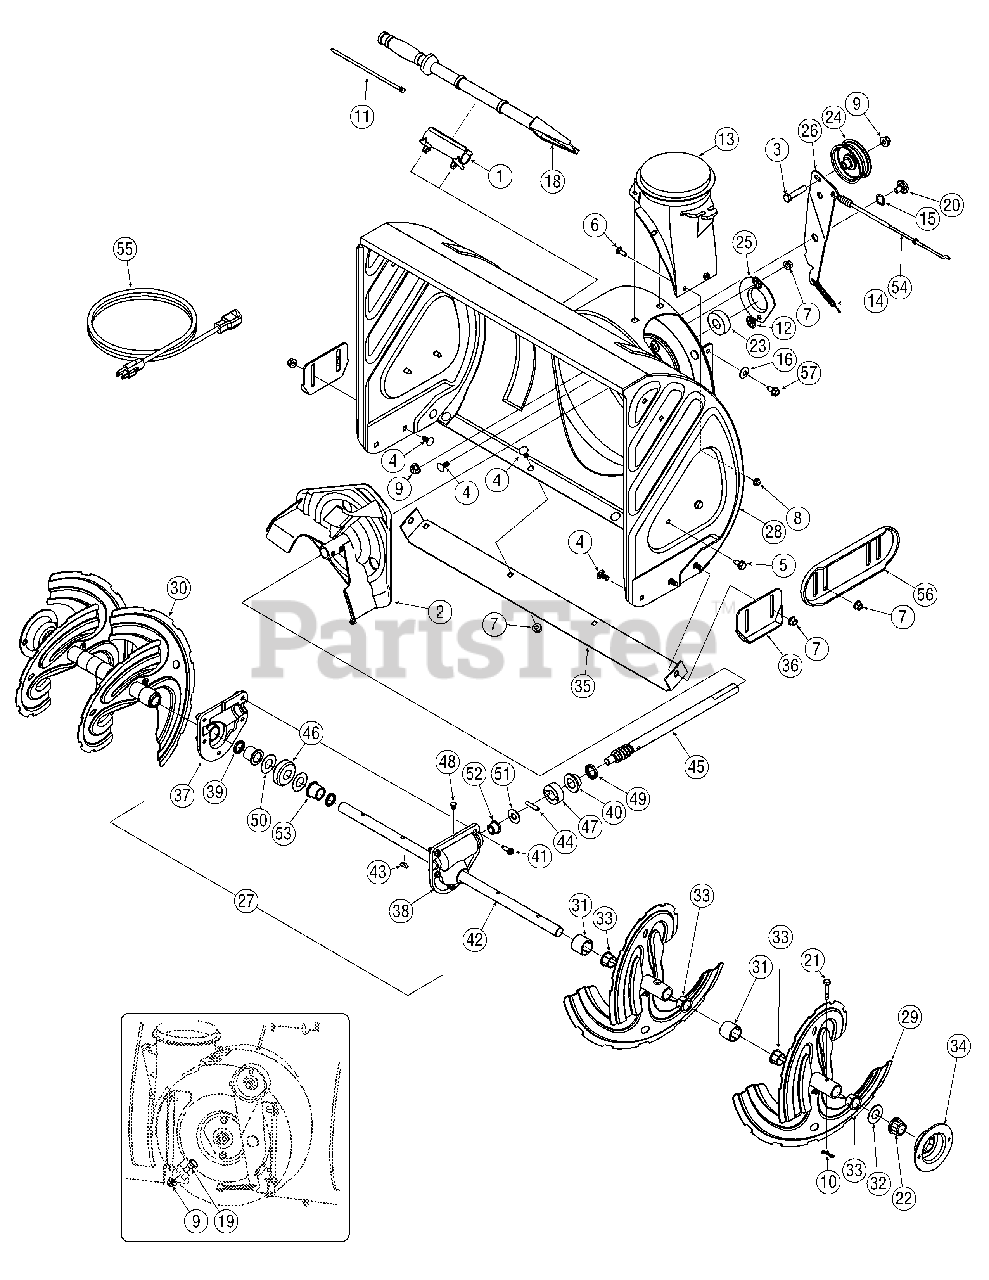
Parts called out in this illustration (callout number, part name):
1	Snow Removal Tool Mount
3	Hex Screw, 3/8-16, 1.75, Gr5
4	Bolt, Carriage, 5/16-18, .750 Gr1
5	Screw, 5/16-18, 0.625
6	Screw, Carriage, 1/4-20, .750, Gr5
7	Nut, Flange Lock, 5/16-18, Nylon
8	Nut, Flange Lock, 1/4-20, Nylon
9	Nut, Flange Lock, 3/8-16, Nylon
10	Cotter Pin, Bow-tie
11	Cable, Tie, 3/16 x .05 x 7.4
12	Nut, Push-on, .25 Dia
13	Chute, Adapter 5" Dia
14	Spring, Extension, .38 OD x 3.6
15	Washer, Wave, .625 x .885 x .015
16	Washer, Bell, .340 x .872 x .060
17	Washer, Flat, .25 x .630 x .0515
18	Snow Removal Tool
19	Screw, Shoulder, .498 x .34, 3/8-16
20	Screw, Shoulder, .625 x .17, 3/8-16
21	Shear Pin, .25 x 1.50
22	Bearing, Hex Flange x .75 ID
23	Bearing, Ball, .75 ID x 1.85 OD
24	Flat Pulley, Idler, 2.75 OD
25	Housing, Bearing, 1.85 ID
27	Gearbox Assembly, Auger, 24"
27	Gearbox Assembly, Auger, 26"
28	Housing Assy Troy-Bilt, Auger 24"
31	Spacer, 1.25 OD x .75 ID x 1.00
32	Washer, Flat, .76 x 1.49 x .06
33	Bushing, Flange, .80 ID x .91 OD
36	Screw, Carriage 5/16-18 x .750
36	Nut, Nylon Lock 5/16-18
36	Nut, Nylon 1/4-20
36	Skid Shoe, Polymer Standard
36	Standard Polymer Reversible Shoe Kit
36	Screw, Carriage 5/16-18 x 1.00
36	Washer, Flat .349 x .879 x .063
36	Skid Shoe, Deluxe Polymer
36	Deluxe Polymer Reversible Shoe Kit
36	Skid Shoe, Stainless Steel
36	Bolt, Carriage 5/16-18 x .750 (SS)
36	Screw, Carriage 5/16-18 x 1.00 (SS)
36	Nut, Hex 5/16-18 (SS)
36	Washer, Bell .340 x 782 x .060 (SS)
37	Housing, Auger, RH Reduced
38	Housing, Auger, LH Reduced
39	Seal, Oil, .750" ID X 1.0" OD X .125"
40	Bearing, Flange, .75 x 1.0 x .59
41	Screw, Self-tapping, 1/4-20, 0.750
42	Axle, Auger, 24"
42	Axle, Auger, 26"
43	Key, Hi-pro 3/16 x 5/8
44	Pin, Dowel, .25 OD x 1.2
45	Shaft, Worm .75 OD
46	Gear, Worm 20T
47	Collar, Thrust
48	Plug, 1/4 x .437
49	Seal, Oil, .750" ID X 1.131" OD X .188"
50	Washer, Flat, .760 ID x 1.5 OD
51	Washer, Flat, .51 x 1.12
52	Bearing, Flange, .75 x 1.0 x .925
53	Bearing, Flange, .75 x 1.00 x .975
54	Clutch Cable, Auger, 47.23"
55	Extention Cord, 110V
57	Screw, 5/16-18, 0.75
